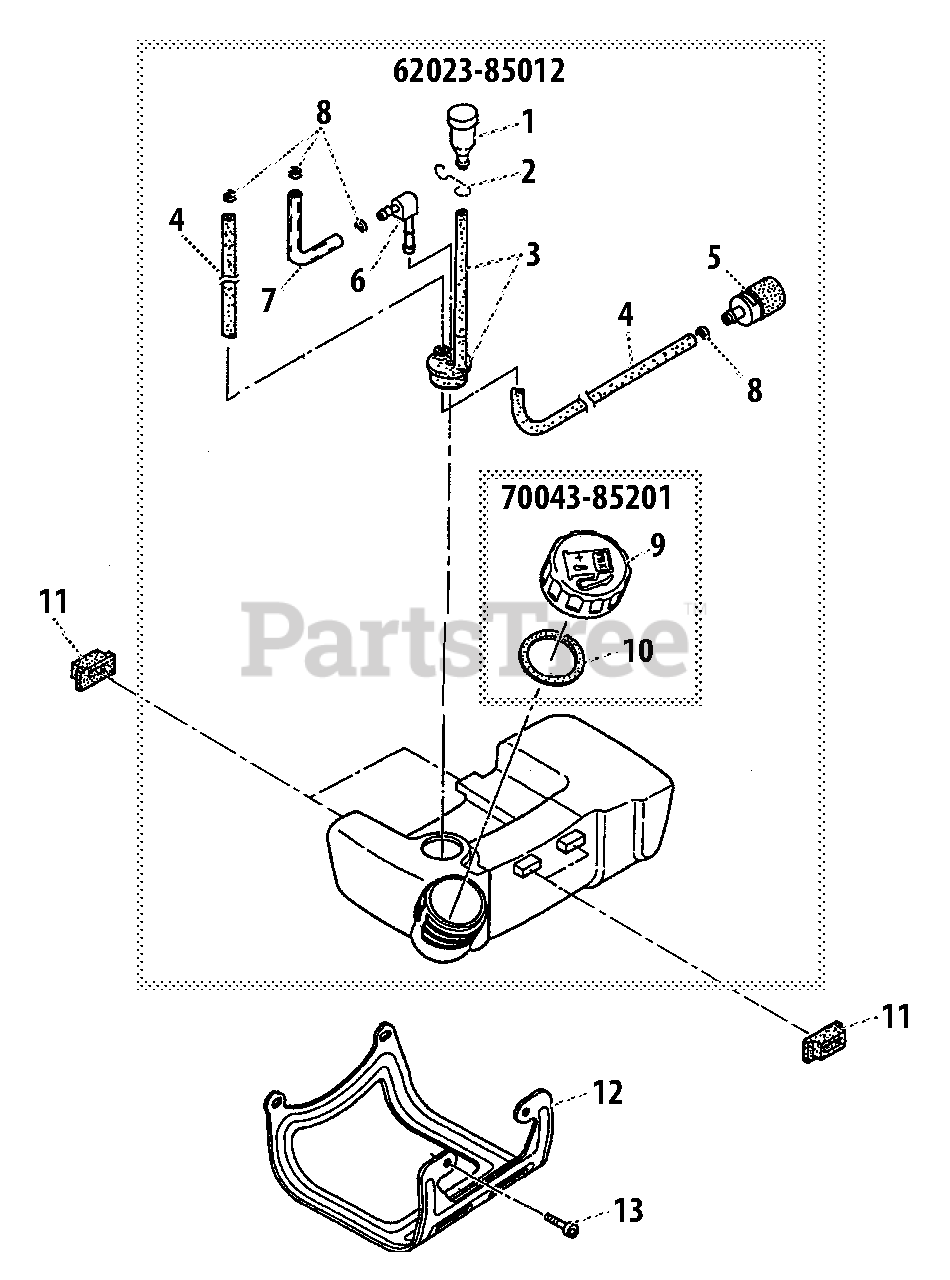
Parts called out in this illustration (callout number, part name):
1	VENT ASSY
2	CLIP, VENT ASSY
3	GROMMET, FUEL W/VENT PIPE
4	PIPE, FUEL
5	FILTER, FUEL 125-528
6	CONNECTOR, PIPE
7	PIPE, FUEL RETURN
8	CLIP Ø6
9	CAP, FUEL
10	GASKET, FUEL CAP
11	CUSHION, FUEL TANK
12	GUARD, METAL FUEL TANK
13	BOLT M5×12
62023-85012	FUEL TANK ASSY
70043-85201	CAP ASSY, FUEL
